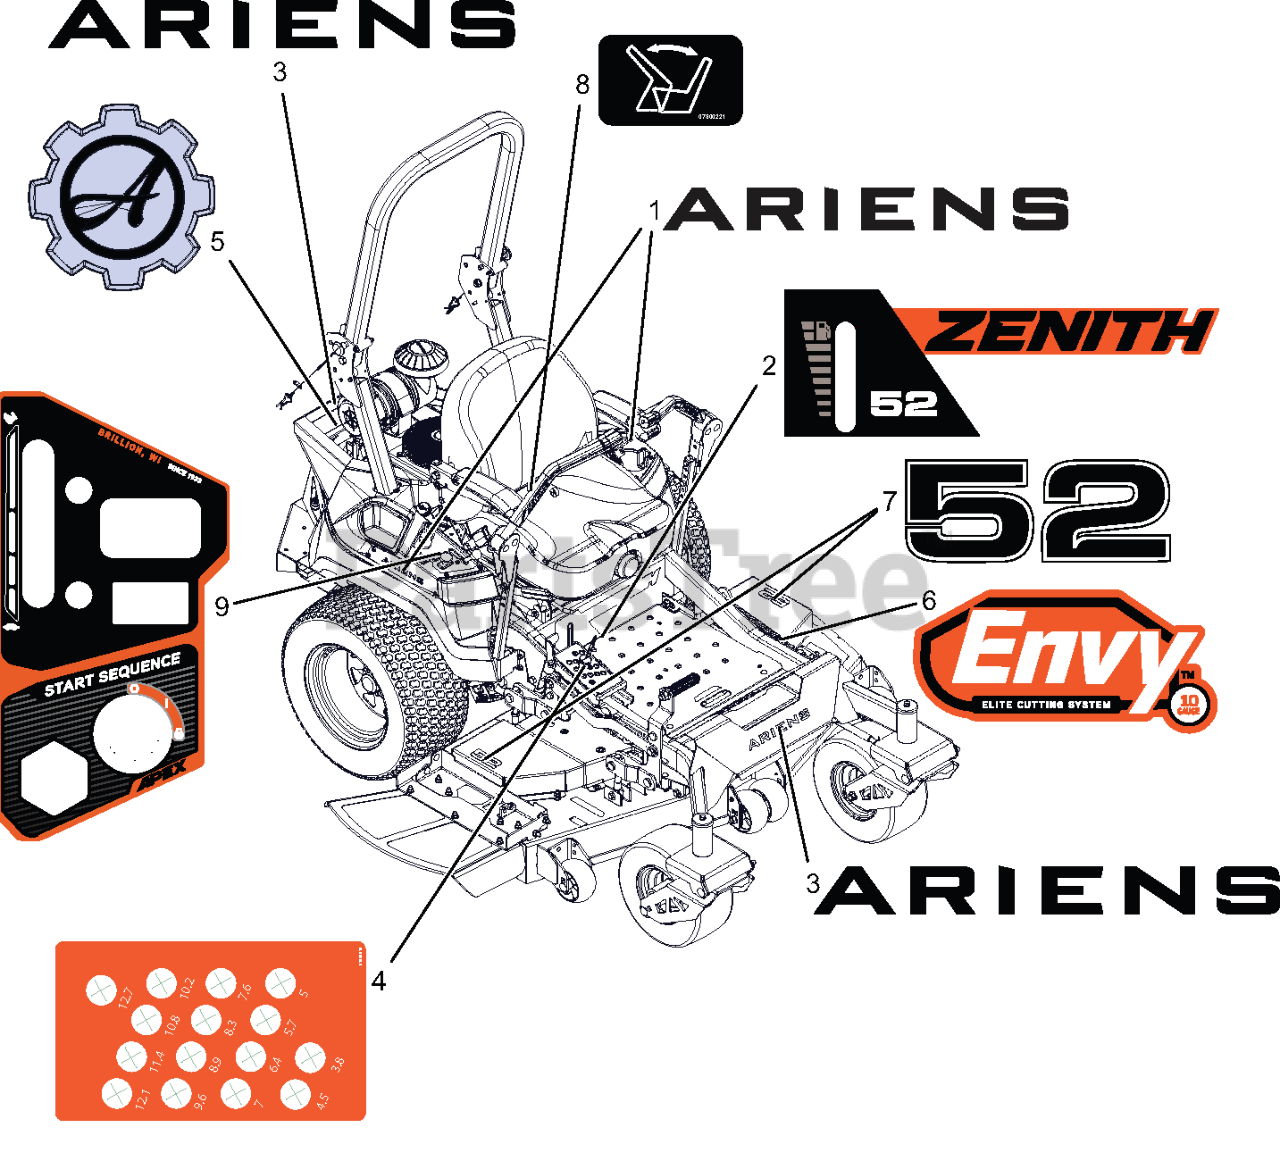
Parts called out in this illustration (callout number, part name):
1	DECAL- ARIENS 6.000" BLACK
2	DECAL- ZENITH 52 KICKPLATE
3	DECAL- ARIENS 9.625" BLACK
4	DECAL, APEX HOC METRIC
5	DECAL- ARIENS GEAR BADGE
6	DECAL- DECK -ENVY
7	DECAL- DECK 52
8	DECAL - SEAT RELEASE
9	DECAL- DASH -APEX & ZENITH
